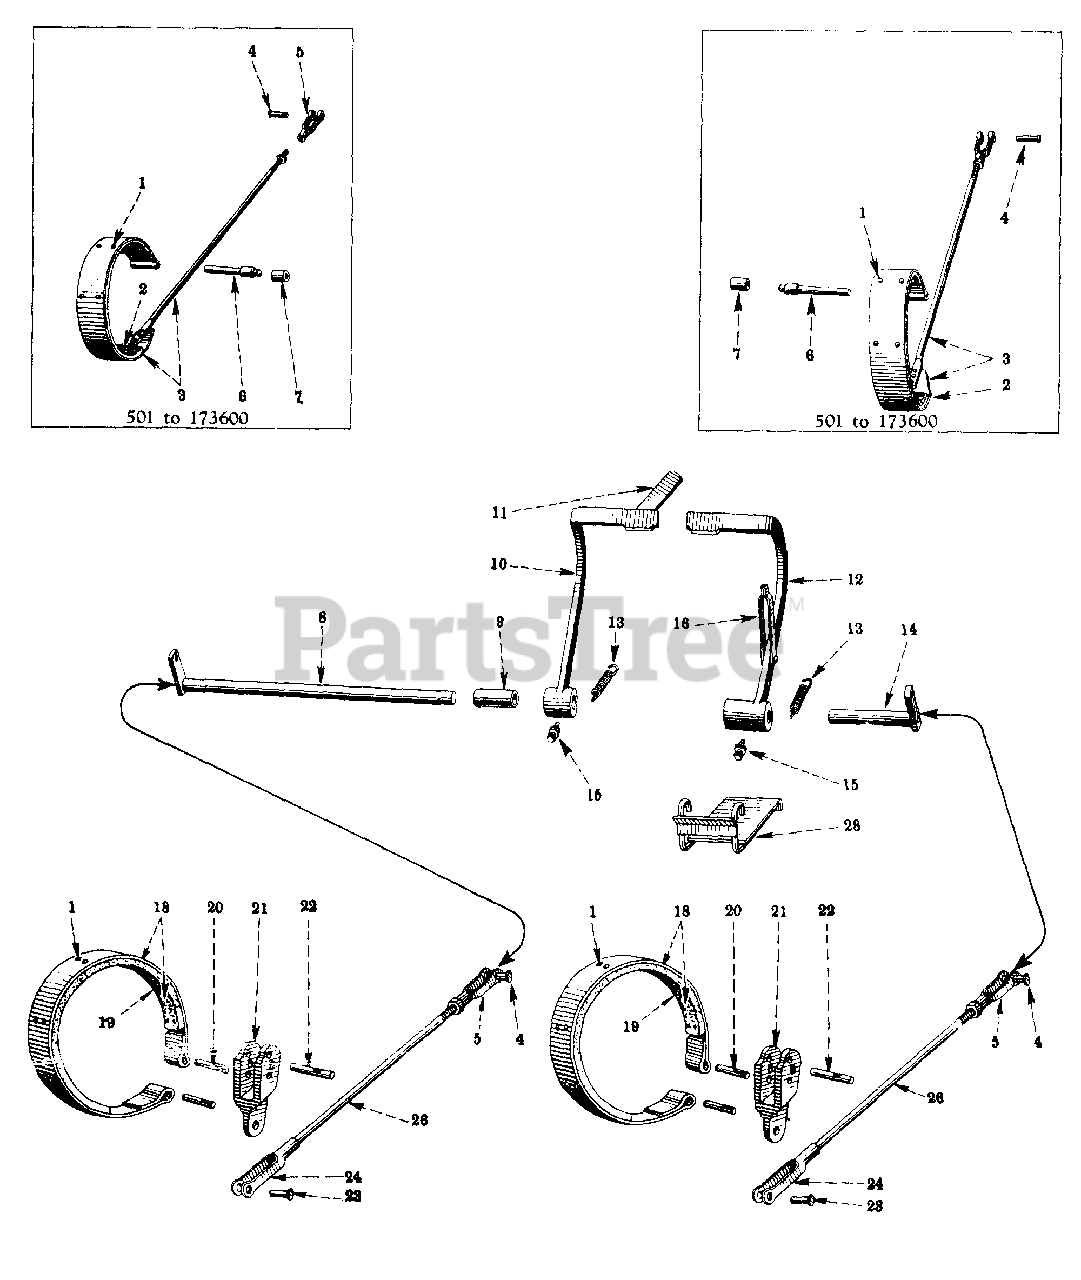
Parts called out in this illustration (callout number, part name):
1	RIVET BRAKE BAND
2	LINING SET, BRAKE
3	BAND ASSY. BRAKE
4	PIN, 5/16 X 15/16 ROD END BRAKE
5	CLEVIS, 5/16-24 ADJ ROD END
6	PIN, BRAKE BAND ANCHOR
7	SPACER, BRAKE BAND
8	SHAFT ASSY. LH BRAKE
9	SPACER, LH BRAKE SHAFT
10	PEDAL ASSY. LH BRAKE
12	PEDAL
13	SPRING, BRAKE PEDAL RETURN
14	SHAFT ASSY, RH BRAKE
15	SCREW BRAKE PEDAL LOCK
16	RATCHET BRAKE
18	BAND
19	PACKAGE, BRAKE LINING SERVICE
20	PIN, BRAKE BAND ANCHOR
21	TOGGLE, LH BRAKE BAND ACTUATING
22	PIN, BRAKE BAND PIVOT
23	PIN, 5/16 X 15/16 ROD END - BRAKE ROD ADJUSTABLE CLEVIS
24	CLEVIS, 5/16-24 ADJ ROD END - BRAKE ROD
26	ROD, BRAKE OPERATING
28	PLATE ASSY. STEP
